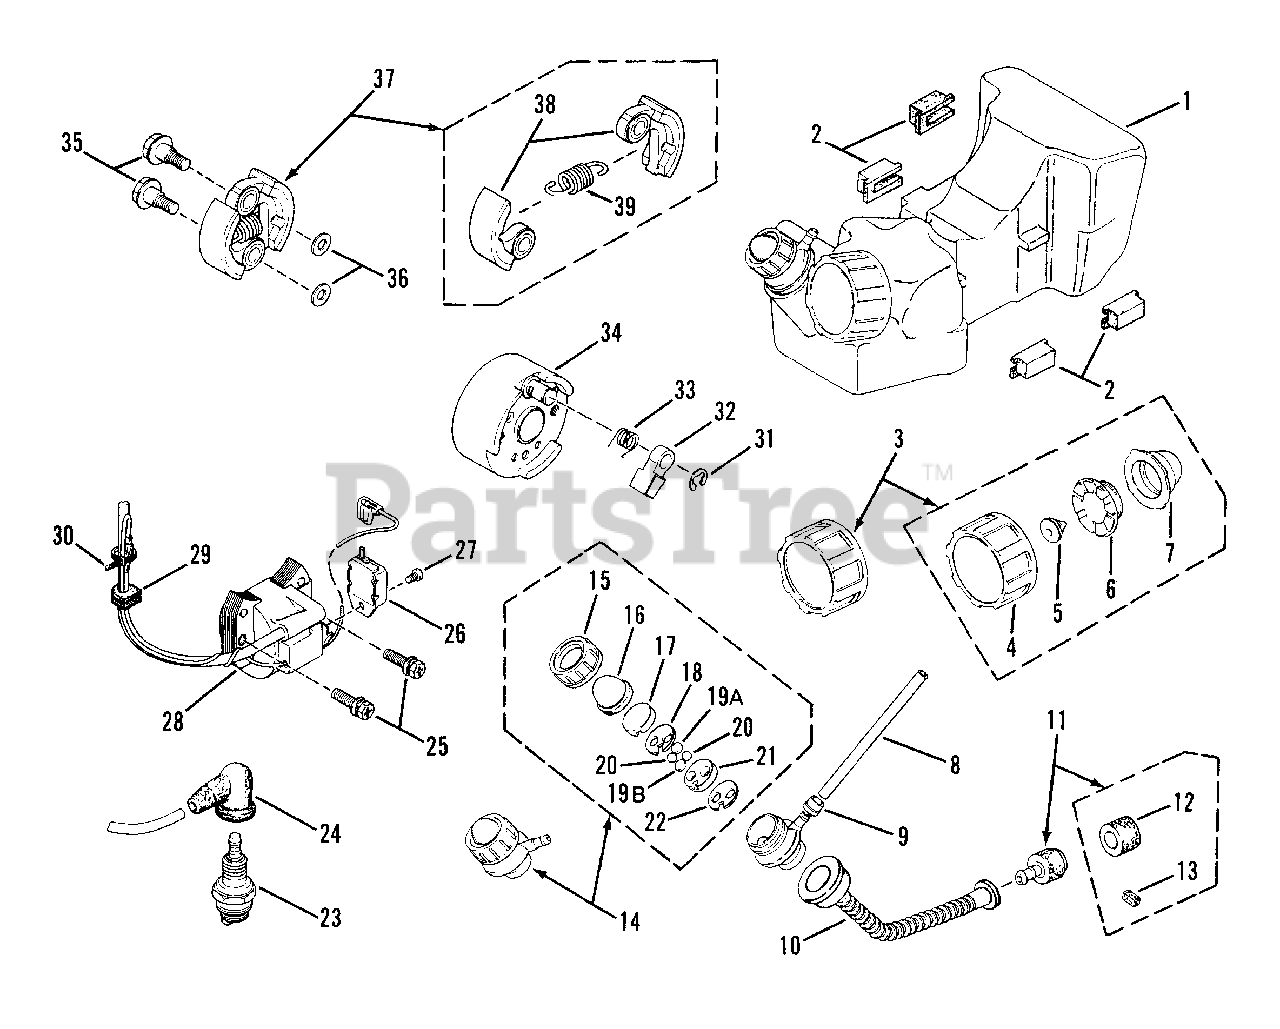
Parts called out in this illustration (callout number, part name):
1	TANK ASSM'Y., Fuel
2	PAD, Fuel Tank
3	CAP ASSMY
4	CAP FUEL
5	VALVE, Breather
7	GASKET
8	TUBE, Fuel
9	CLIP, Fuel Tube
10	HOSE, Fuel
11	FILTER ASSM'Y., Fuel
14	PRIMER PUMP ASSMY
15	CAP, Pump
16	CAP, Rubber
17	SEAT, Valve B
21	SEAT, Valve A
23	SPARK PLUG
24	BOOT, Spark Plug
25	BOLT/WASHER
26	UNIT, Transistor
28	COIL, Ignition
29	GROMMET
30	BAND
31	SNAP RING
32	RATCHET
33	SPRING, Ratchet
35	BOLT, Clutch
37	CLUTCH ASSMY
38	SHOE, Clutch
